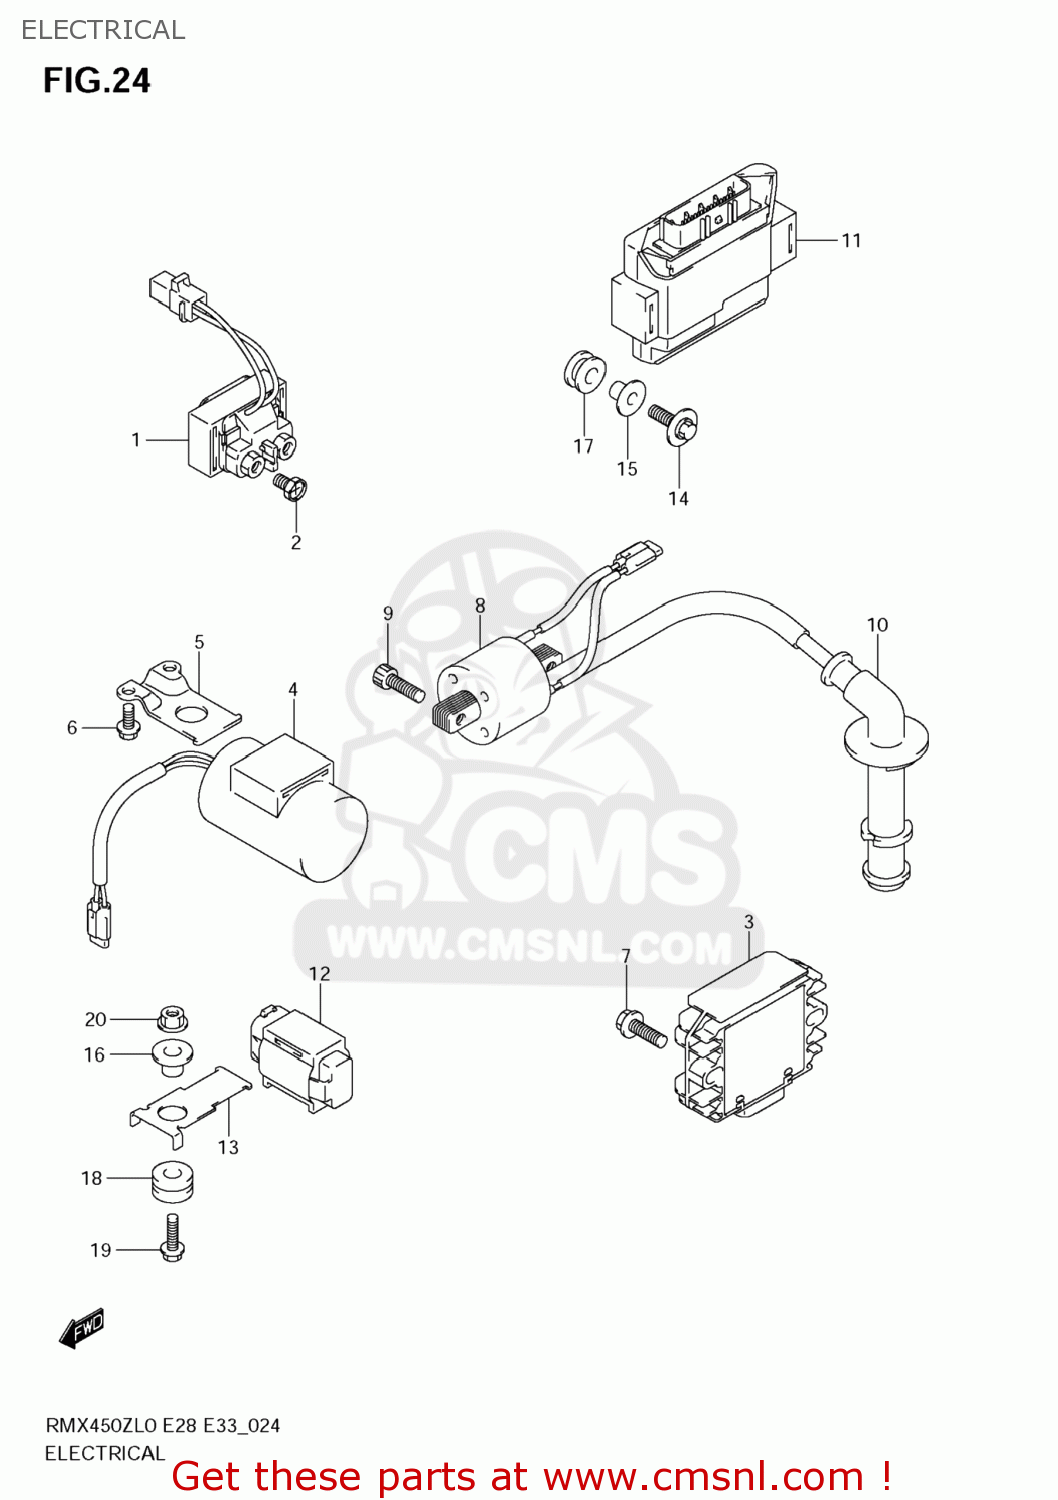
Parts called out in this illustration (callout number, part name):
1	RELAY ASSY,STARTING MOTOR
2	SCREW(6X8)
3	RECTIFIER ASSY
4	CONDENSER ASSY
5	BRACKET,CONDENSER
6	BOLT(6X10)
7	SCREW
8	COIL ASSY,IGNITION
9	BOLT
10	CAP ASSY,SPARK PLUG
11	CONTROL UNIT,F
12	SENSOR ASSY,FUEL CUT
13	BRACKET,FUEL CUT SENSOR
14	BOLT(6X20)
15	SPACER(6.2X8.4X10.9)
16	SPACER(6.2X8.4X10.9)
17	GROMMET
18	CUSHION
19	BOLT
20	NUT
